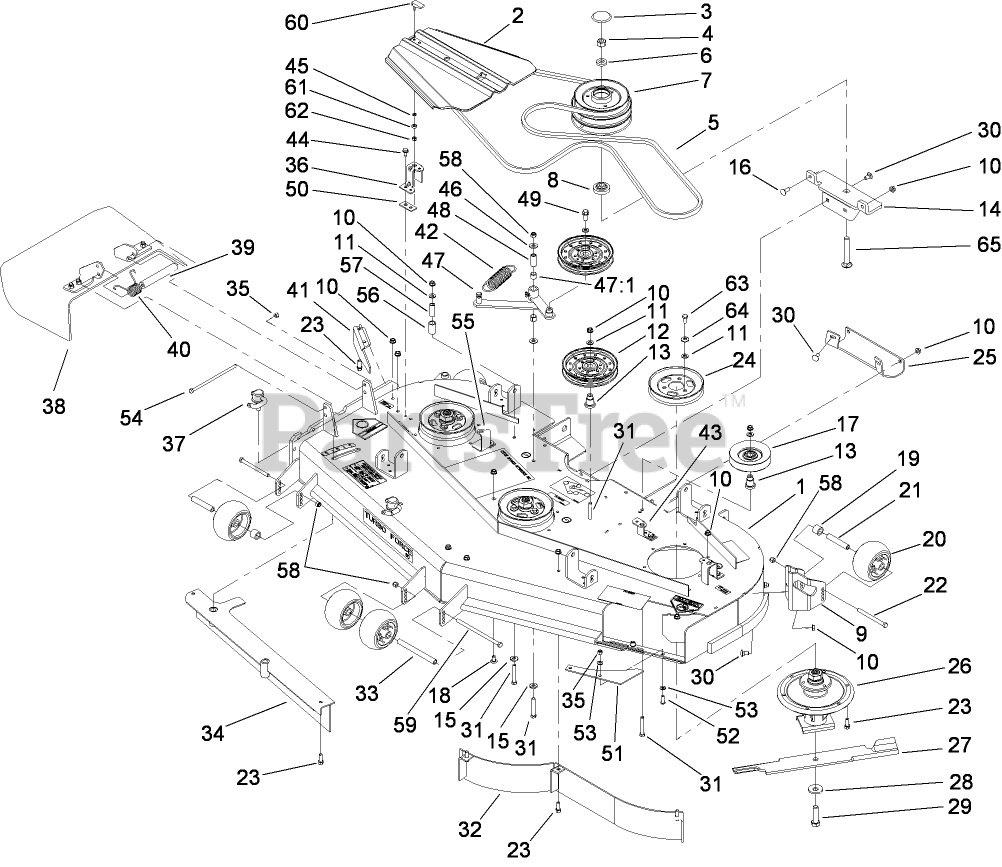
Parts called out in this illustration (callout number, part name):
1	DECK DECAL ASM
2	COVER-BELT
3	CAP-PLASTIC
4	NUT-HEX
5	BELT-V
6	SPACER
7	PULLEY AND BEARING ASM
8	SPACER-FLANGED
9	MOUNT-WHEEL, LH
10	NUT-HHF, WHIZ
11	WASHER-FLAT
12	Idler-Flat
13	MOUNT-PULLEY
14	MOUNTING BRACKET ASM
15	WASHER-BELLEVILLE
16	BOLT-CARR
17	PULLEY-IDLER
18	SCREW-CARR
19	TUBE-SPACER
20	ROLLER-SCALP, ANTI
21	TUBE-SPANNER
22	SCREW-HH
23	SCREW-HWH
24	Pulley
25	Plate-Skid
26	SPINDLE ASM
27	BLADE-HI FLOW
28	Washer-Blade Bolt, Heavy
29	SCREW-BLADE
30	SCREW-CARR
31	SCREW-HH
33	SPACER-WHEEL
35	NUT-LOCK, NI
36	BRACKET-COVER
37	LEVER ASM
38	RUBBER DEFLECTOR ASM
39	SPACER
40	SPRING-TORSION
41	BAFFLE-DISCHARGE
42	SPRING-EXTENSION
43	BRACKET-COVER, TALL
44	SCREW-HWHTF
45	WASHER
46	WASHER-FLAT
47	IDLER ARM ASM
47:1	SLEEVE-BEARING
48	BUSHING
49	SCREW-HHF
50	SPACER-COVER, BELT
51	PLATE-TURBO
52	SCREW-HSBH
53	WASHER-SPRING
54	SCREW-HH
55	BRACKET-COVER
56	SPACER-RUBBER
57	SPACER-PIVOT, IDLER
58	NUT-LOCK, NI
59	SCREW-HH
60	HANDLE-LATCH, SWELL
61	BUSHING-LATCH, SWELL
62	NUT-LOCK, HH
63	SCREW-HH
64	WASHER-BELLEVILLE
65	BOLT-CARRIAGE
